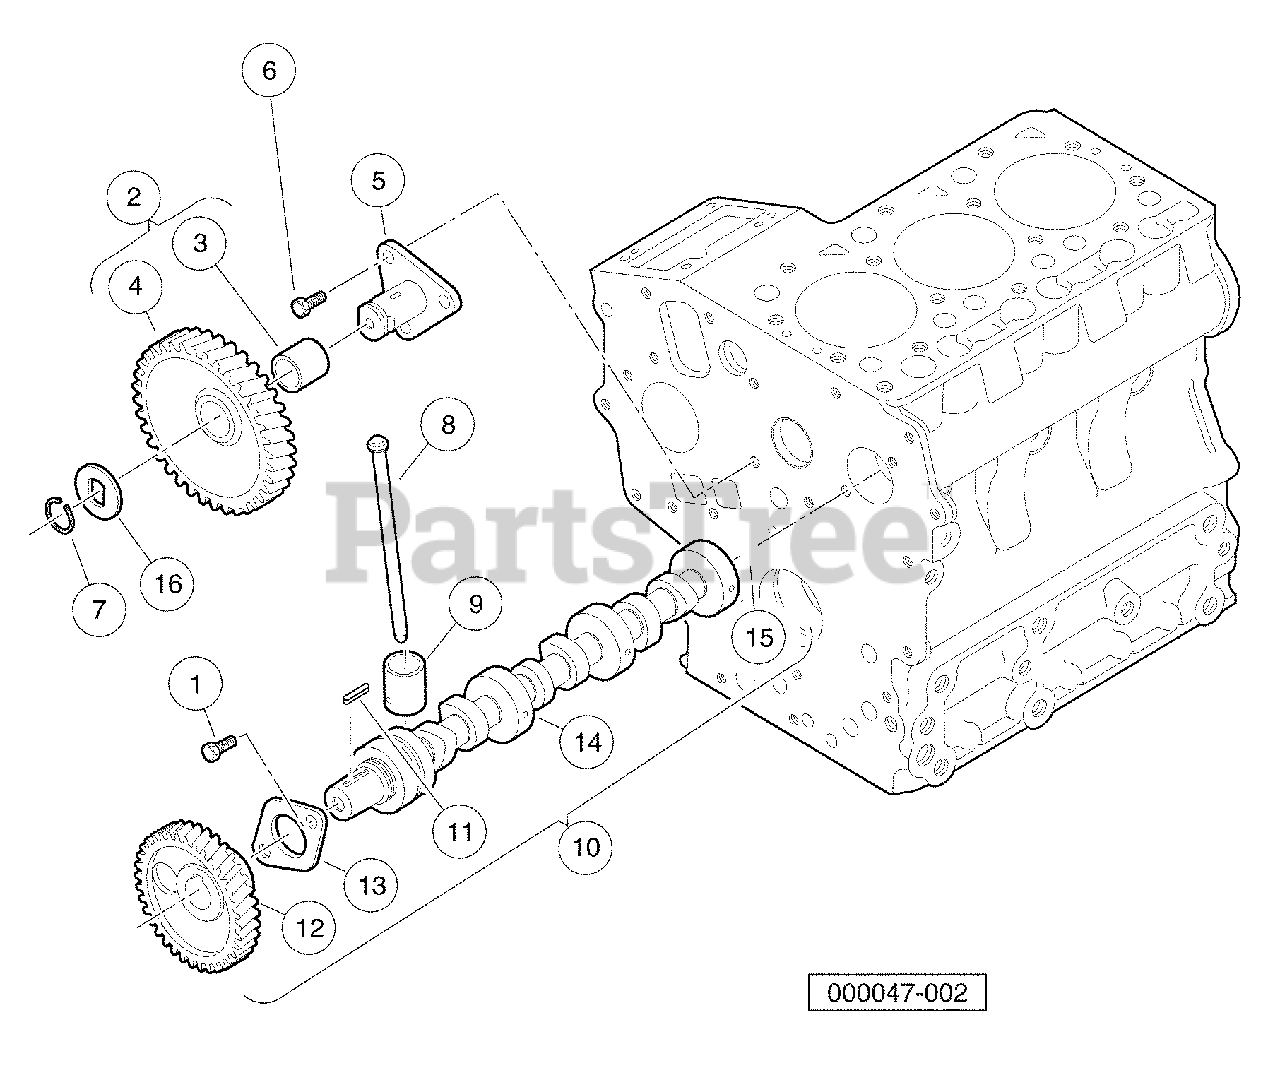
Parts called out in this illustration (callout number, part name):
1	Bolt, D722, Cam End
2	Gear, Idle
3	Bushing, D722 Idle Gear
4	Gear, Idle.
5	Shaft, Idle Gear
6	Bolt, M6 X 1 X 14
7	Ring, Snap
10	Assy Camshaft, Long
11	Key, Feather, Long Camshaft
13	Stopper, Camshaft
14	Camshaft.
15	Ball, Check
16	Collar, Idle Gear
